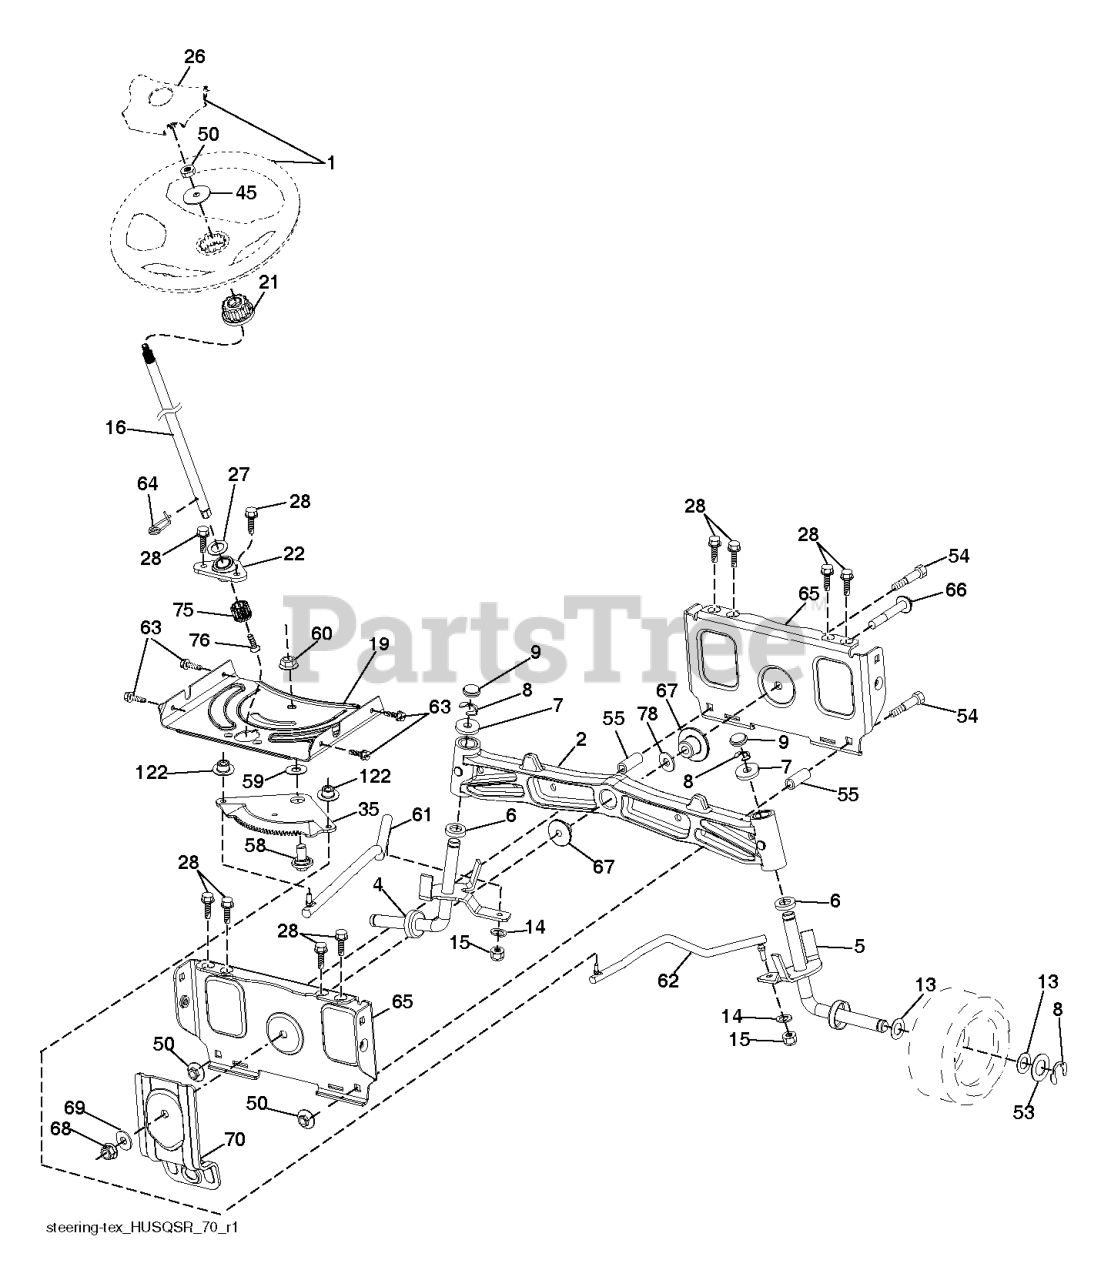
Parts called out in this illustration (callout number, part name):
1	Service Kit
2	AXLE.SVC.ASM CAST IRON.TEX
4	SPINDLE.WLDMT.LH.16IN.TEX.X431
5	SPINDLE.WLDMT.RH.16IN.TEX.X431
6	WASHER THRUST
9	CAP.SPINDLE.BLACK
15	NUT CROWNLOCK 3/8-24
16	KIT.SRVC.STEERINGSHAFT.2HISHFT
19	SERVICE KIT PLATE PLATE.STEER.
21	KIT.SRVC.STEERINGSHAFT.ADAPTER
22	KIT.SRVC.STEERINGSHAFT.LWRBSHG
28	SCREW, 3/8-16X3/4
35	GEAR.SECTOR.PLATE.DDL.
45	WASHER.3/8ID.2-3/8OD.12GA.PLTD
50	NUT.HEX.FLANGE.3/8-16.LOCKNUT
53	WASHER.HARDENED
55	SPACER.BRACE.AXLE
58	BOLT.SHOULDER.SECTOR.P
59	WASHER.THURST.SECTOR.S
60	NUT.FLANGE.LOCK.5/8-11
61	Links
62	Links
63	BOLT.HEX.HD.WASHER.5/16-18X.75
64	RETAINER.CLIP.SPRING.S
65	BRACE.AXLE.FRONT.NLT/N
66	BOLT HEX FGHD 7/16-14 X 3 SERR
67	BUSHING
68	NUT.LOCK.FLANGE.7/16
69	WASHER.1.5X.505X.118
70	BRACKET FRONT DECK SUSPENSION
75	KIT.SRVC.STEERINGSHAFT.PINION
76	SCREW HEAD SOCKET LRVB
78	THRUST WASHER
122	CAP.GEAR.SECTOR.TEX
